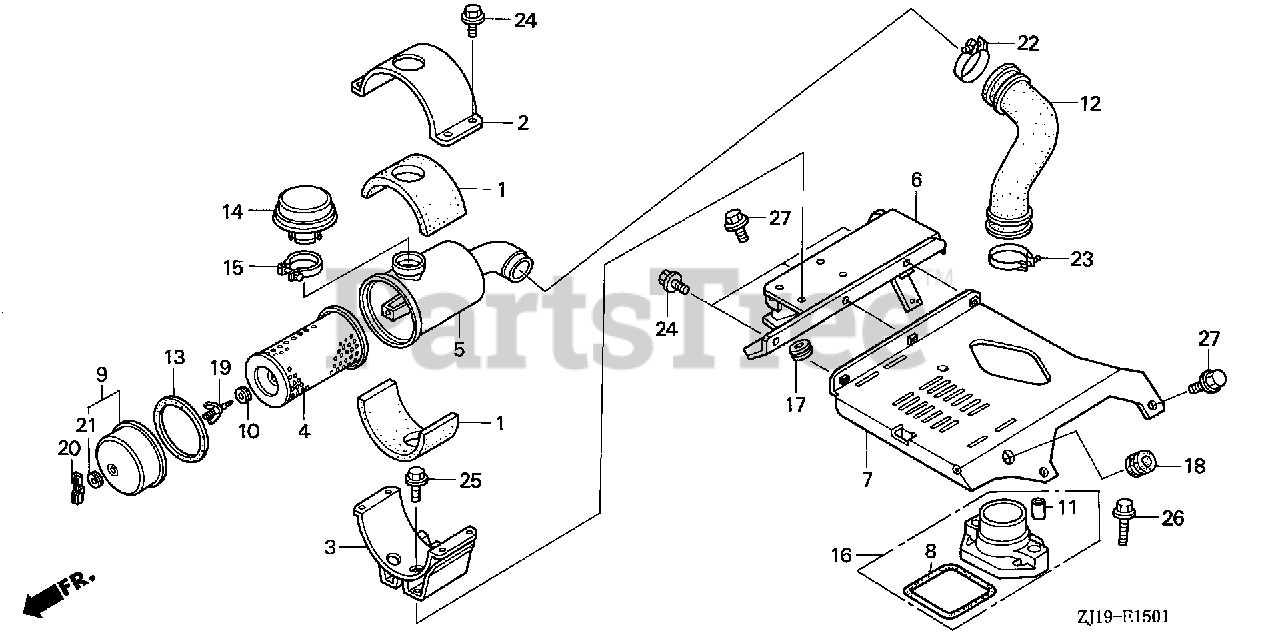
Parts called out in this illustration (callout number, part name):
1	RUBBER, AIR CLEANER HOLDER (UPPER)
2	HOLDER COMP., AIR CLEANER (UPPER)
3	SEAL, AIR CLEANER HOUSING
4	ELEMENT COMP., AIR CLEANER
5	HOUSING COMP., AIR CLEANER (SNORKEL)
6	STAY COMP. A, AIR CLEANER (SNORKEL)
7	STAY COMP. B, AIR CLEANER (SNORKEL)
8	SEAL, AIR CLEANER HOUSING
9	COVER COMP., AIR CLEANER
10	GROMMET, AIR CLEANER
11	COLLAR A, AIR CLEANER
12	TUBE, AIR CLEANER CONNECTING
13	SEAL, AIR CLEANER
14	CAP COMP., IN.
15	CLAMP ASSY.
16	JOINT ASSY., CONNECTING TUBE (B)
17	GROMMET, RESERVE TANK
18	GROMMET
19	BOLT, AIR CLEANER
20	WINGNUT (6MM)
21	WASHER, AIR CLEANER
22	BAND, AIR CLEANER CONNECTING TUBE (50)
23	BAND, AIR CLEANER CONNECTING TUBE (58)
24	BOLT, FLANGE (6X12)
25	BOLT, FLANGE (6X16)
26	BOLT, FLANGE (6X28)
27	BOLT, FLANGE (8X20)
